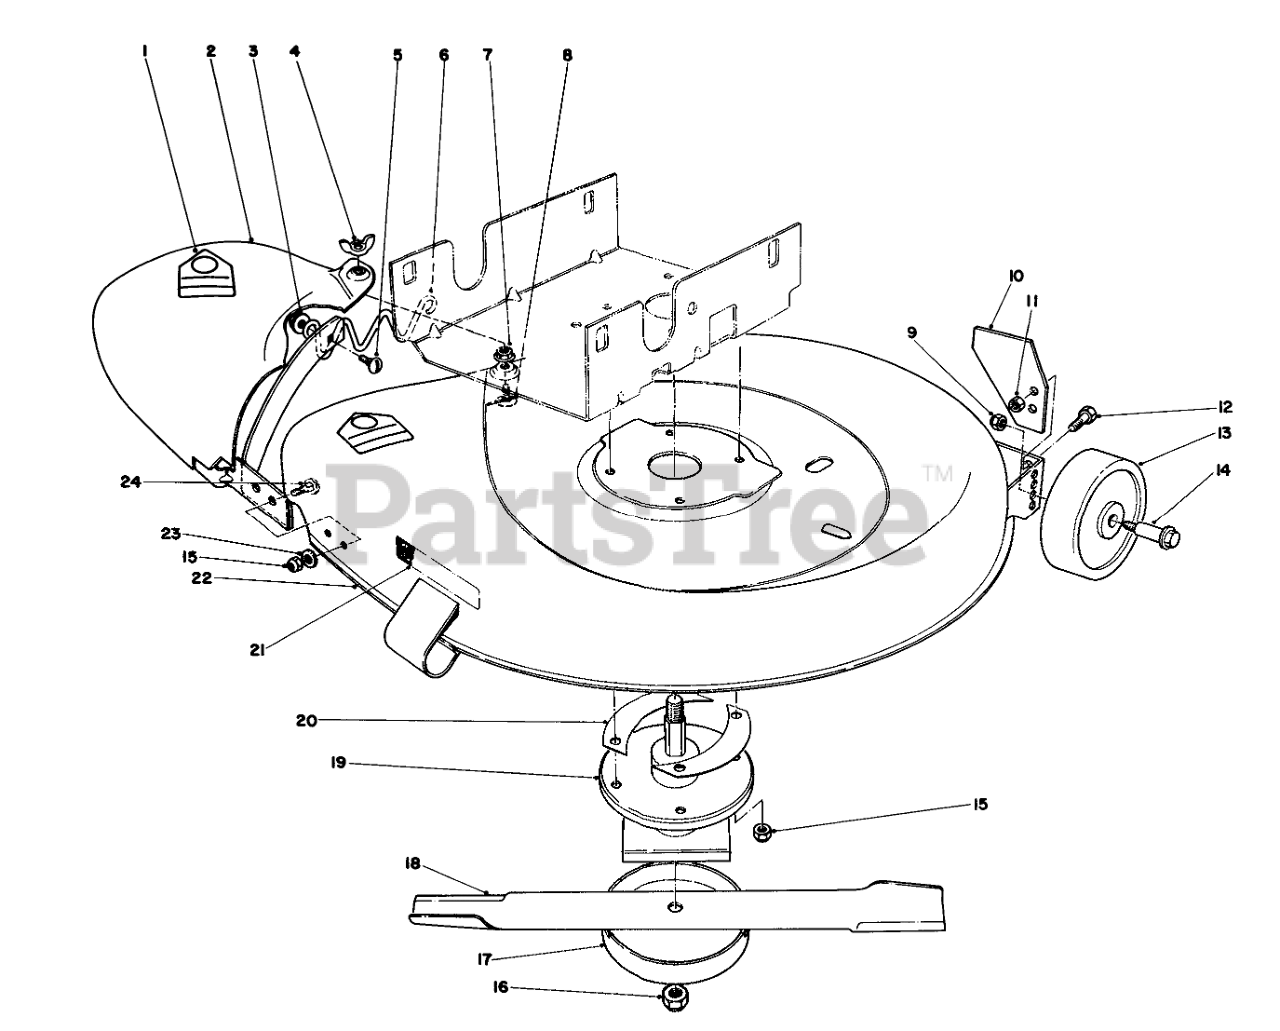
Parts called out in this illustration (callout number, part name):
1	DECAL-DANGER
2	DEFLECTOR WA R
3	NUT-LOCK, HHF
4	Wing Nut
5	SCREW-CARRIAGE
6	FOOT GUARD BRKT
7	PAL NUT
8	Carriage Bolt
9	NUT-LOCK, NI
10	Deck Stop
11	NUT-LOCK, CONE
12	SCREW-HH
13	DECK WHEEL
14	BOLT-WHEEL
15	NUT-LOCK, NI
17	Cup
18	Blade
19	Mower Spindle
20	Shim-Deck Spindle
21	Decal-Deck Inst.
22	HOUSING WA R
23	WASHER-FLAT
24	BOLT-CARR
